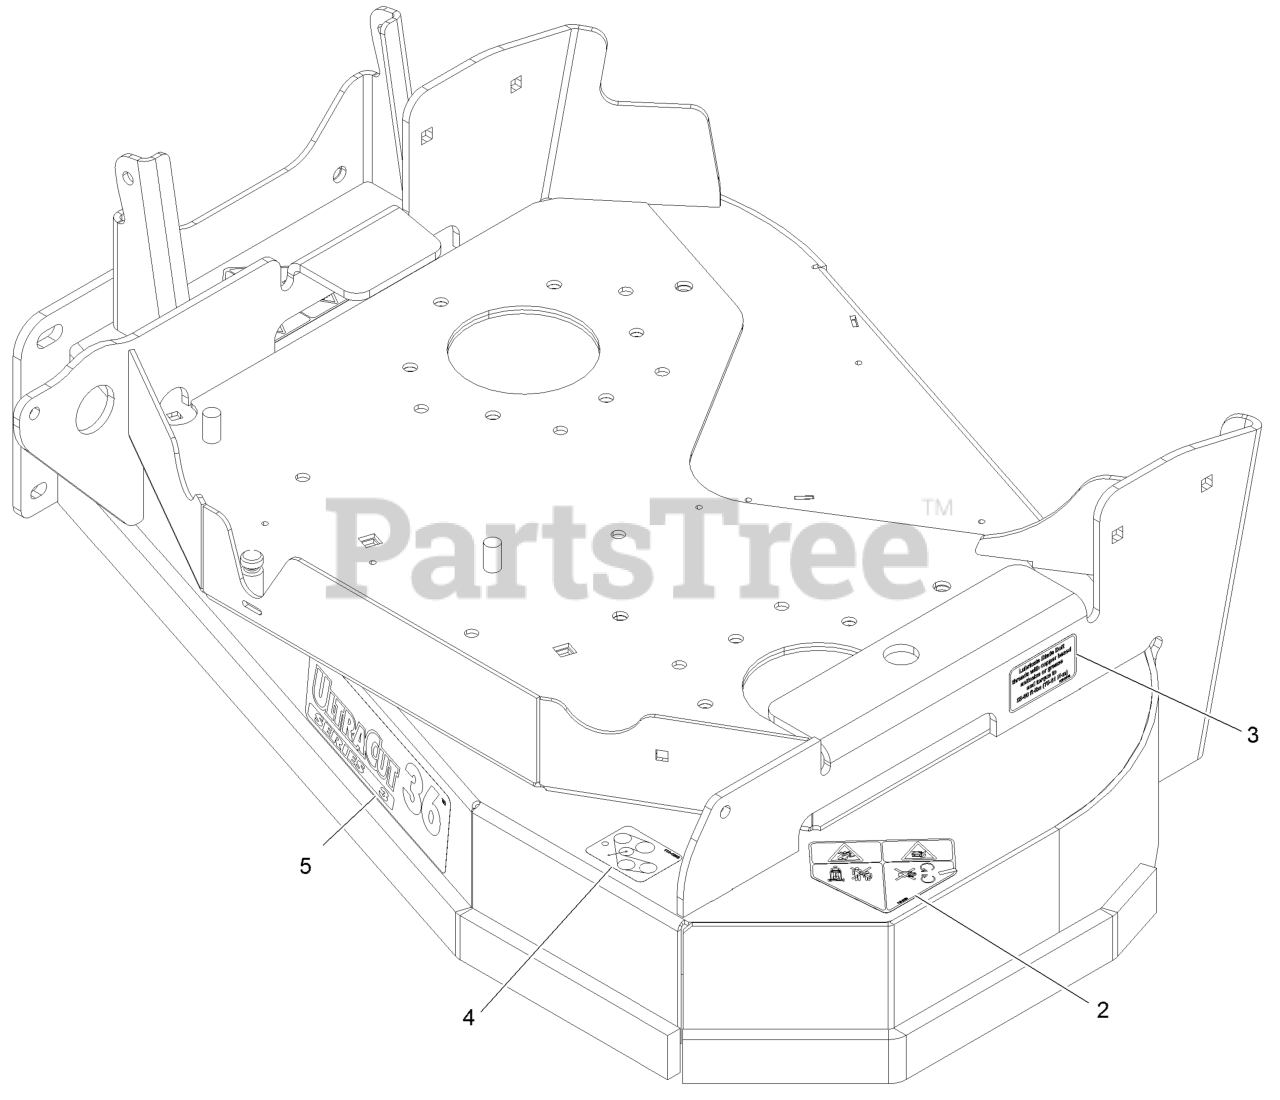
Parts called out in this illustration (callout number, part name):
2	DECAL-DANGER
3	DECAL,BOLT TORQUE
4	DECAL-BELT ROUTING 36
5	DECAL-ULTRACUT 36 SERIES
